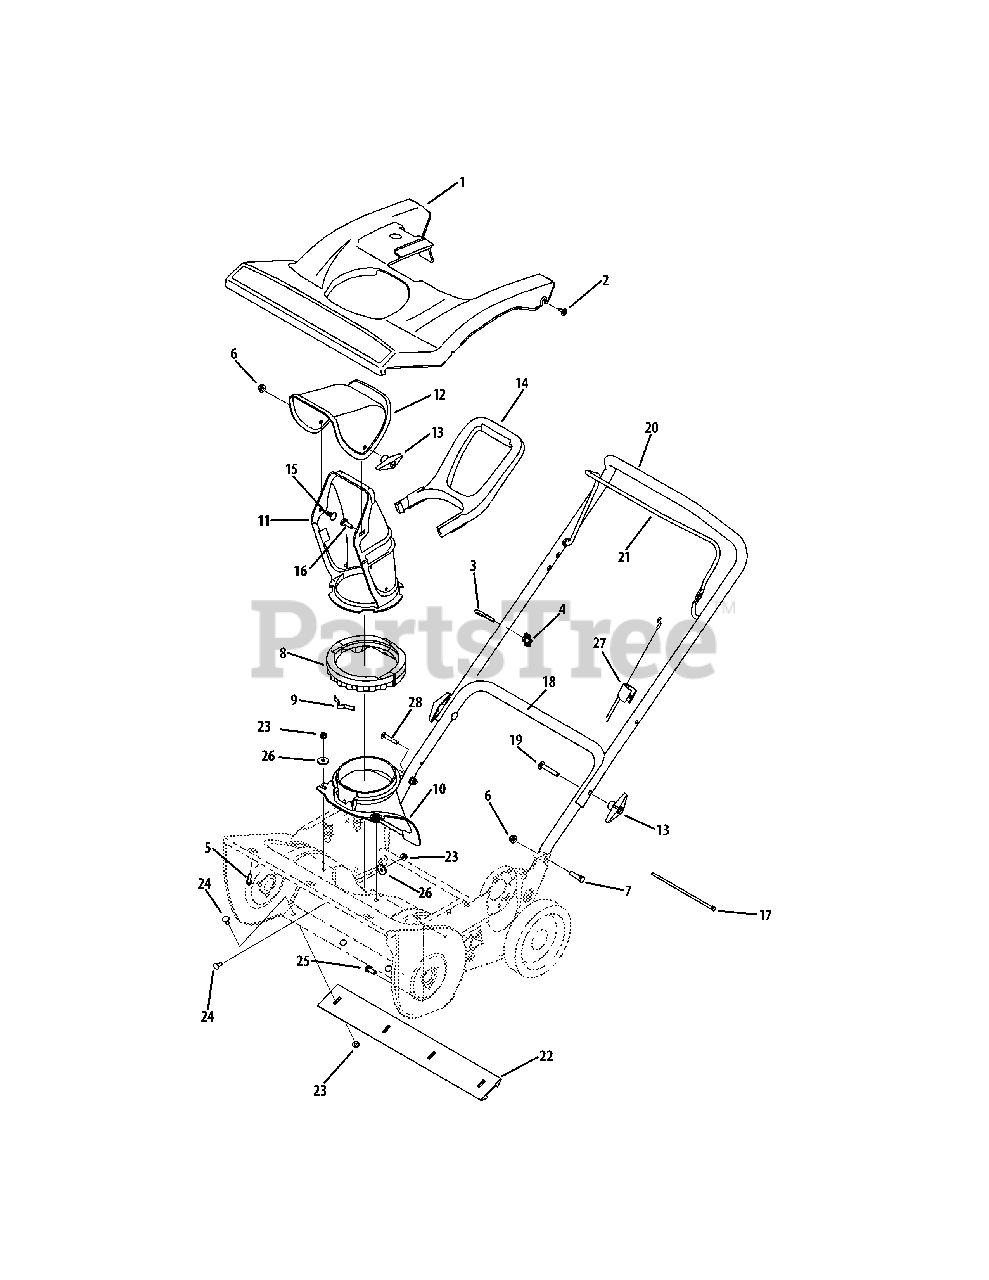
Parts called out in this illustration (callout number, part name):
1	Shroud
2	Hex Washer Screw, 10-16 x .625
3	Eye Bolt, 1/4-20
4	Knob Handle
5	Hex Washer Screw, 1/4-15 x .750
6	Flange Lock Nut, 5/16-18
7	Hex Screw, 5/16-18 x 1.25
8	Lower Chute Ring
9	Chute Adjustment Spring
10	Chute Adapter
11	Lower Chute, 5" Diameter
12	Upper Chute
14	Chute Handle
15	Carriage Bolt, 5/16-18 x .750
16	Carriage Bolt, 5/16-18 x 1.00
17	Cable Tie, 3/16 x .05 x 7.4
19	Carriage Screw, 5/16-18 x 2.00
20	Gullwing Handle
21	Gullwing Control Bail
22	Shave Plate, 21"
23	Flange Lock Nut, 1/4-20
24	Carriage Screw, 1/4-20 x .62
25	Hex Screw, 5/16-18 x .75
26	Flat Washer, .265 x .938 x .120
27	Clutch Cable
28	Hex Screw, 5/16-18 x 1.50
